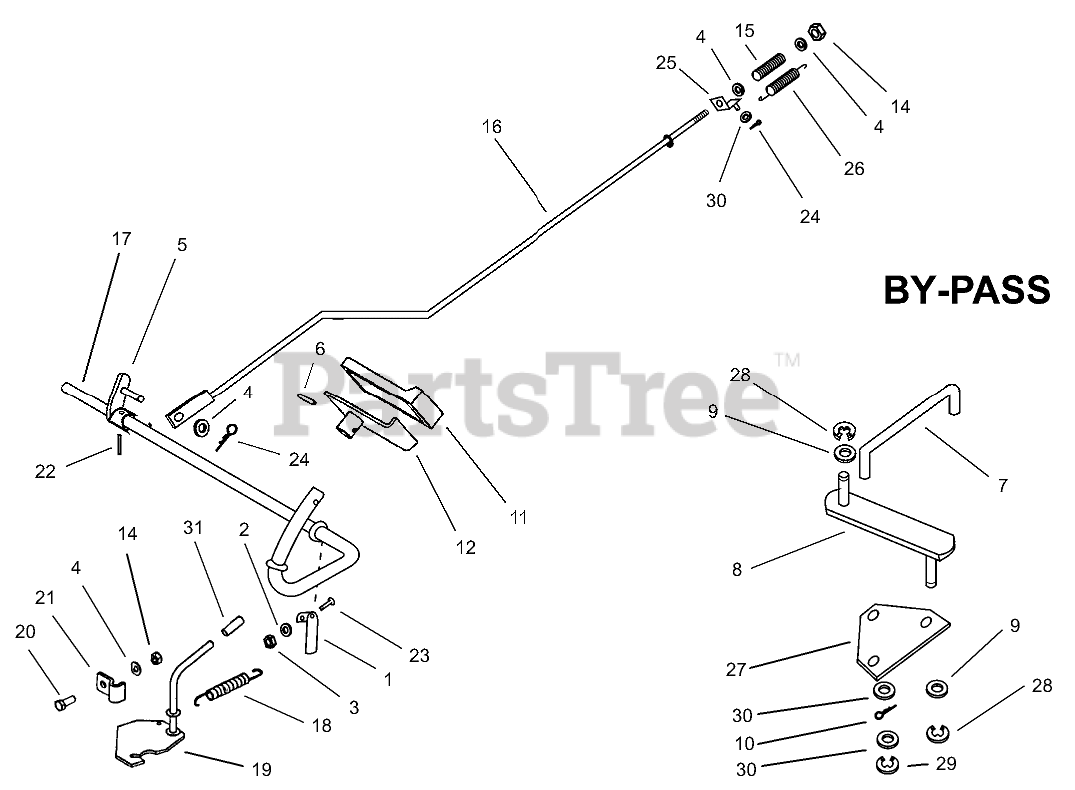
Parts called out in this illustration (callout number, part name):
1	LEVER-SPRING
2	WASHER
3	NUT-HEX
4	WASHER-PLAIN
5	BRACKET-ROD, BRAKE
6	PIN-SPRING
7	ROD-LEVER, BYPASS
8	ARM-BYPASS LEVER
9	WASHER
10	PIN-COTTER
11	PAD-PEDAL
14	NUT-LOCK, NI
15	SPRING-BRAKE
16	ROD-CONNECTING, BRAKE
17	SHAFT-BRAKE
18	SPRING-BRAKE, HAND
19	LEVER-BRAKE, HAND
20	SCREW-HH
21	CLAMP-LEVER, PARKING BRAKE
22	PIN-SPRING
23	SCREW-HEX
24	PIN-COTTER
25	BRACKET-ROD, BRAKE
26	SPRING
27	PLATE-BY-PASS
28	STIRRUP
29	E-CLIP
30	WASHER-FLAT
